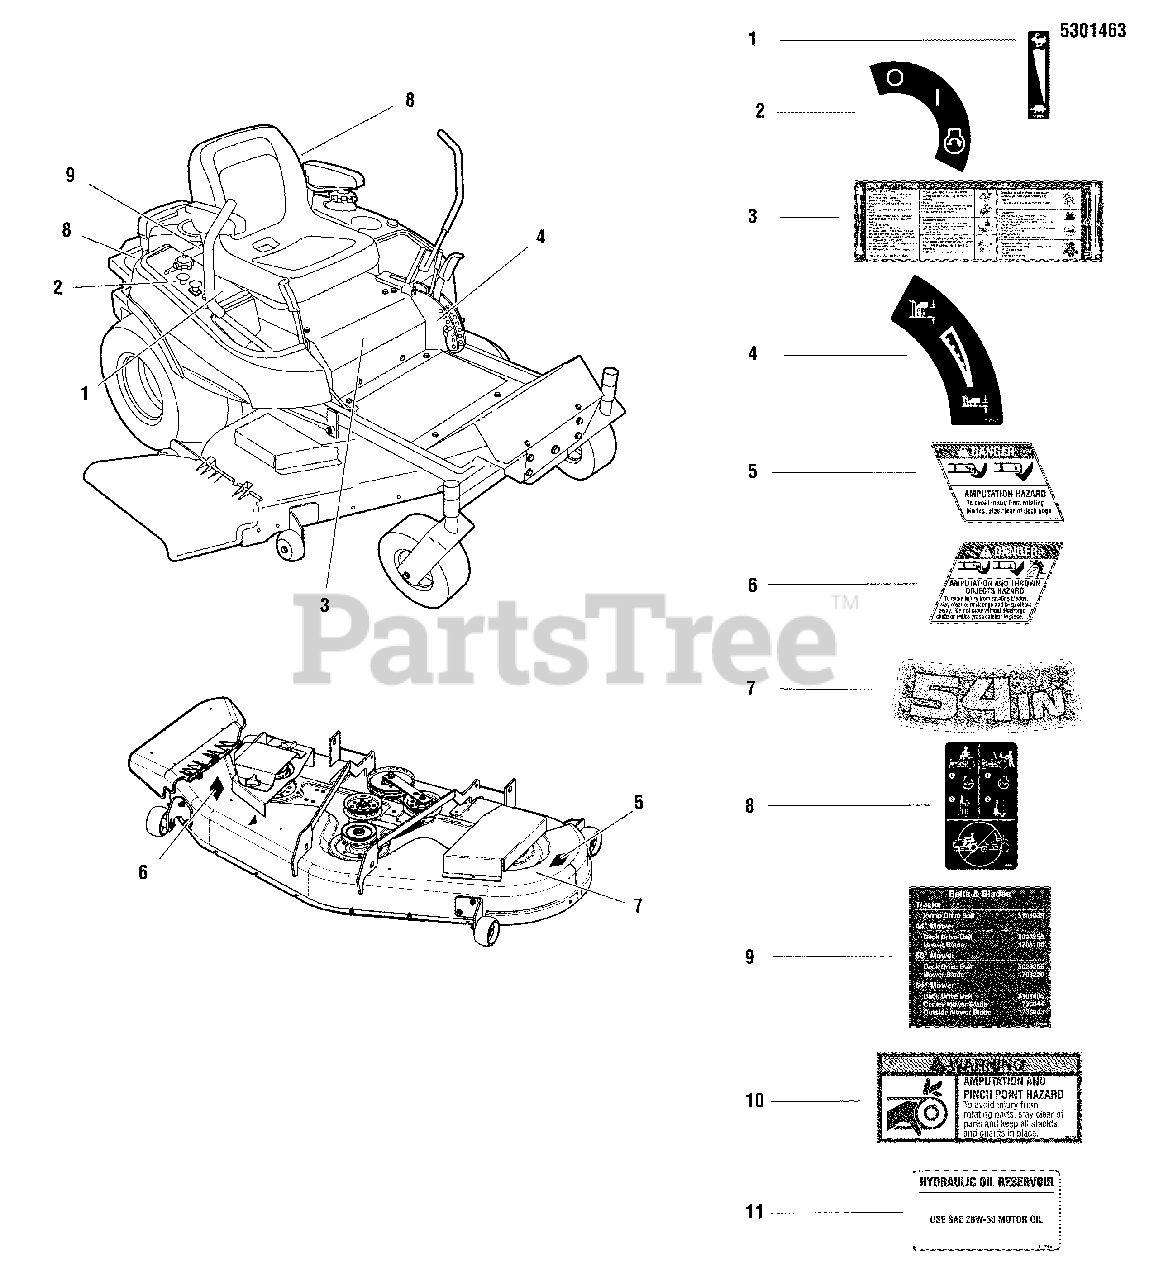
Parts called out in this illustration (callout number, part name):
1	DECAL, THROTTLE CONTROL
2	DECAL, IGNITION SWITCH
3	DECAL, MAIN
4	DECAL, HEIGHT OF CUT
5	DECAL, DANGER, MOWER
6	DECAL, DANGER, MOWER DISCHARGE
7	DECAL, 54"
8	DECAL, TRANSAXLE RELEASE
9	DECAL, BELT & BLADE SNAPPER
10	DECAL, WARNING
11	DECAL, HYDRAULIC OIL, SAE 20W50
